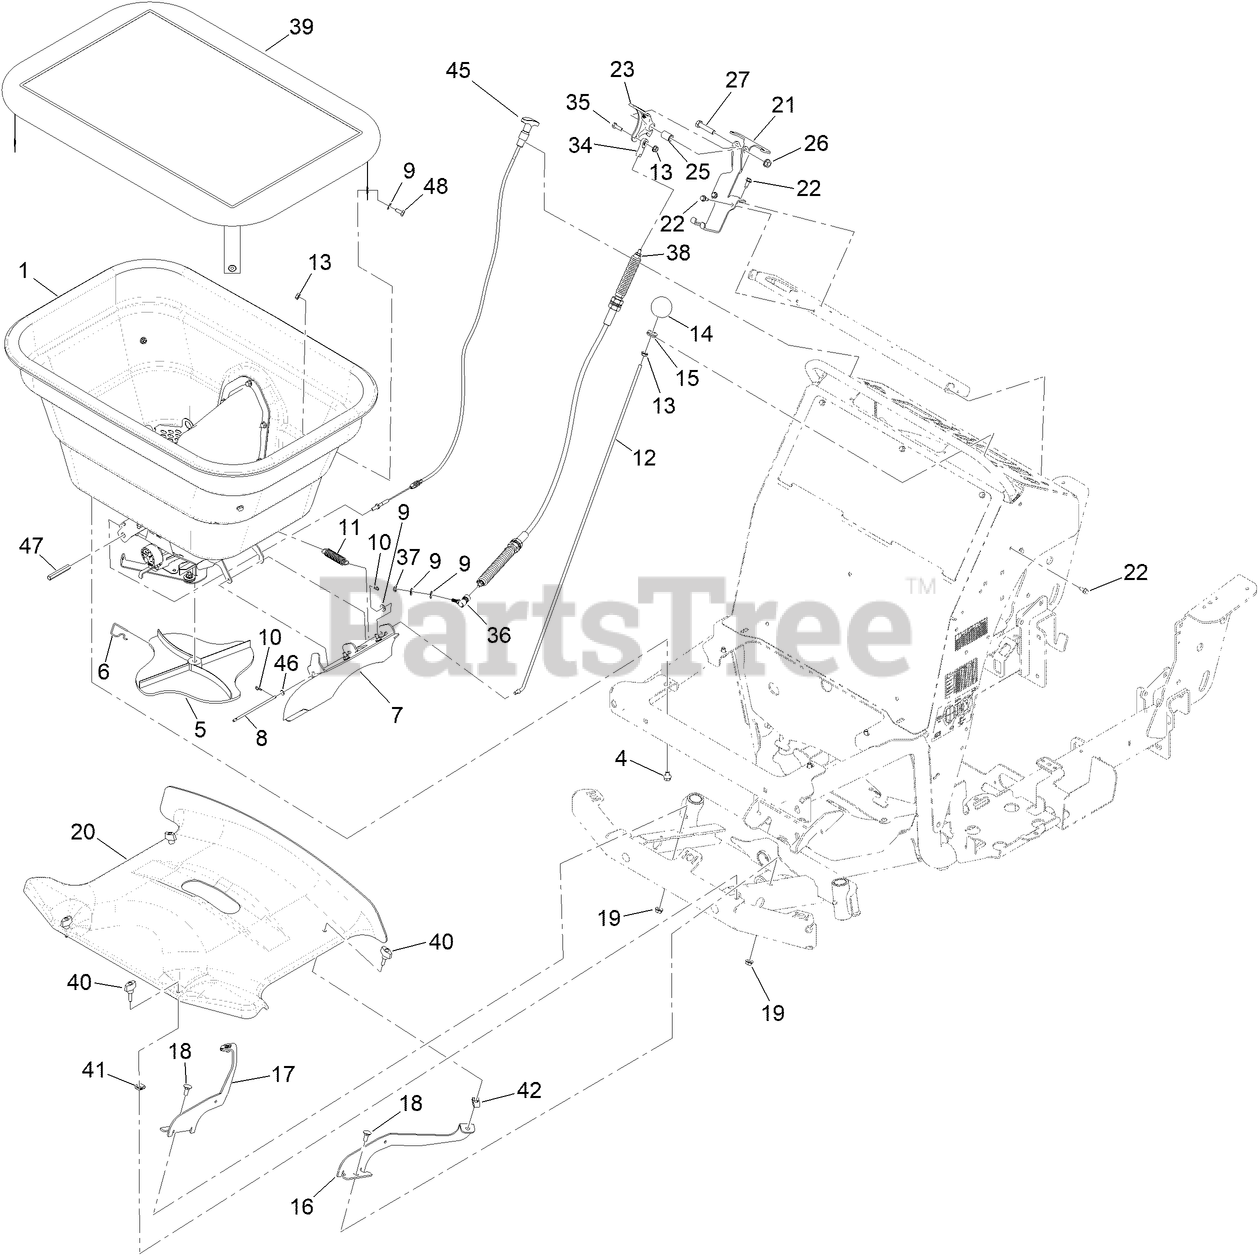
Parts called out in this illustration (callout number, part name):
1	SPREADER HOPPER ASM
4	SCREW-HHF
5	SPINNER-SPREADER
6	CLIP-SPINNER
7	SIDE DEFLECTOR ASM
8	PIN-DEFLECTOR
9	WASHER-FLAT
10	PIN-COTTER, HAIR
11	SPRING-EXTENSION
12	ROD-CONTROL, DEFLECTOR
13	NUT-HF
14	KNOB-RATE, FLOW
15	GROMMET
16	BRACKET-COVER, FRONT (LH)
17	BRACKET-COVER, FRONT (RH)
18	SCREW-CARR
19	NUT-HF
20	COVER-FRONT, SPREADER/SPRAYER
21	MOUNT-HANDLE, FERT GATE
22	SCREW-HWH
23	LEVER-SPREAD, WIDE
25	SPACER
26	NUT-HF
27	SCREW-HH
34	ROD END-BALL JOINT
35	SCREW-HH
36	BALL-JOINT
37	NUT-HEX, NI
39	COVER-HOPPER
40	KNOB-T
41	NUT-RETAINER, U STYLE
42	NUT-RETAINER
45	CABLE-CONTROL, TURN LOCK
46	WASHER-FLAT
47	POST-HEX, DIFFUSER GUIDE
48	SCREW-HH
